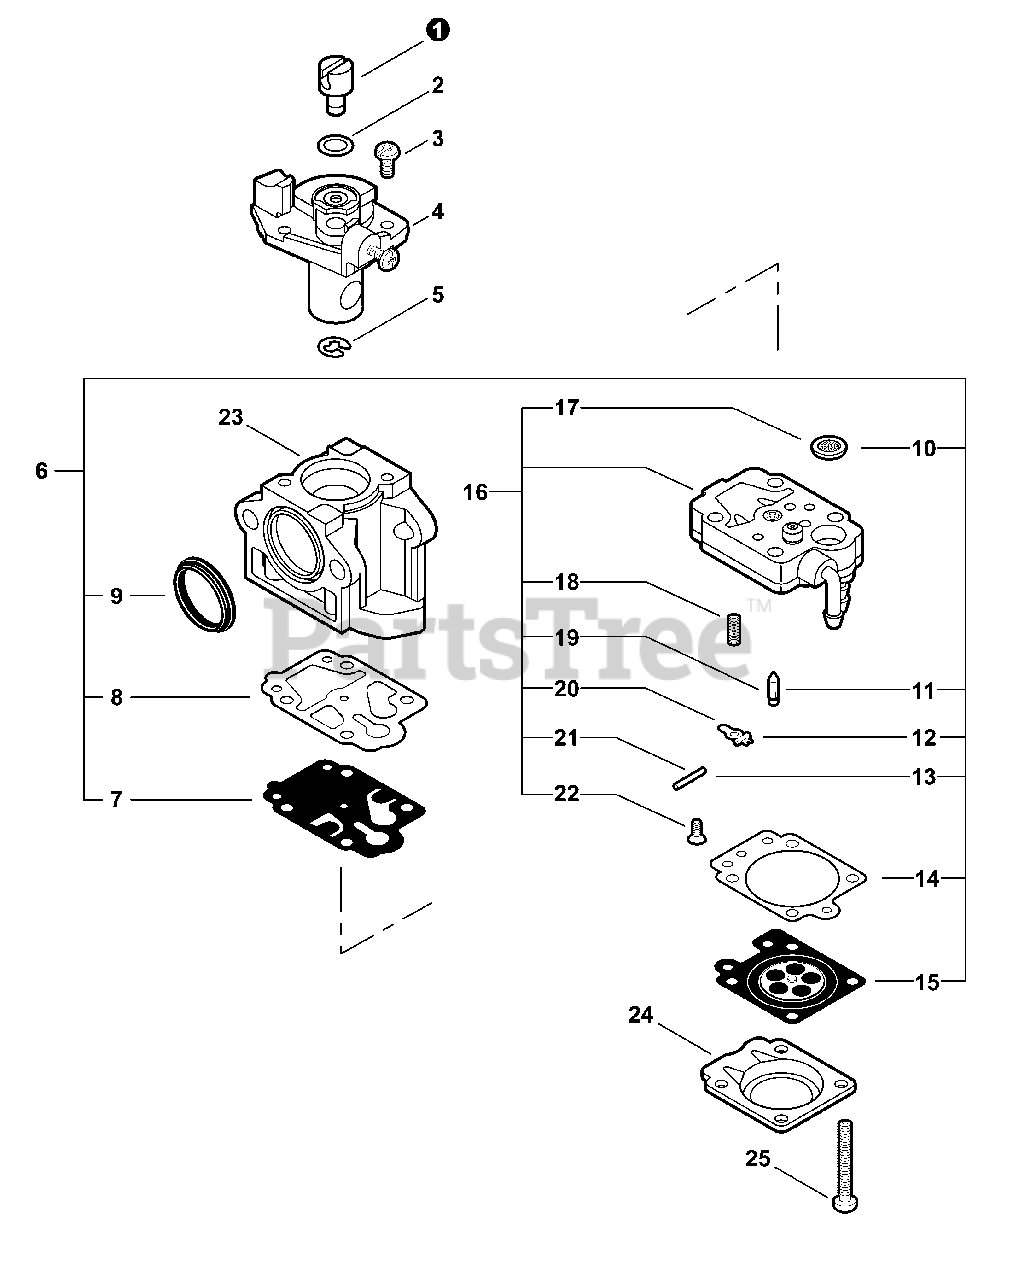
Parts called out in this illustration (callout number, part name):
4	ROTOR COVER ASSY
5	RING, RETAINING
6	REPAIR KIT
7	DIAPHRAGM, PUMP
8	GASKET, PUMP
9	RING, PACKING
10	STRAINER
11	VALVE, INLET NEEDLE
12	LEVER, METERING
13	PIN, METERING LEVER
14	GASKET, METERING
15	DIAPHRAGM, METERING
16	PUMP BODY ASSY
17	STRAINER
18	SPRING, METERING LEVER
19	VALVE, INLET NEEDLE
20	LEVER, METERING
21	PIN, METERING LEVER
22	SCREW, METERING LEVER PIN
23	BODY, CARBURETOR
24	COVER, METERING
